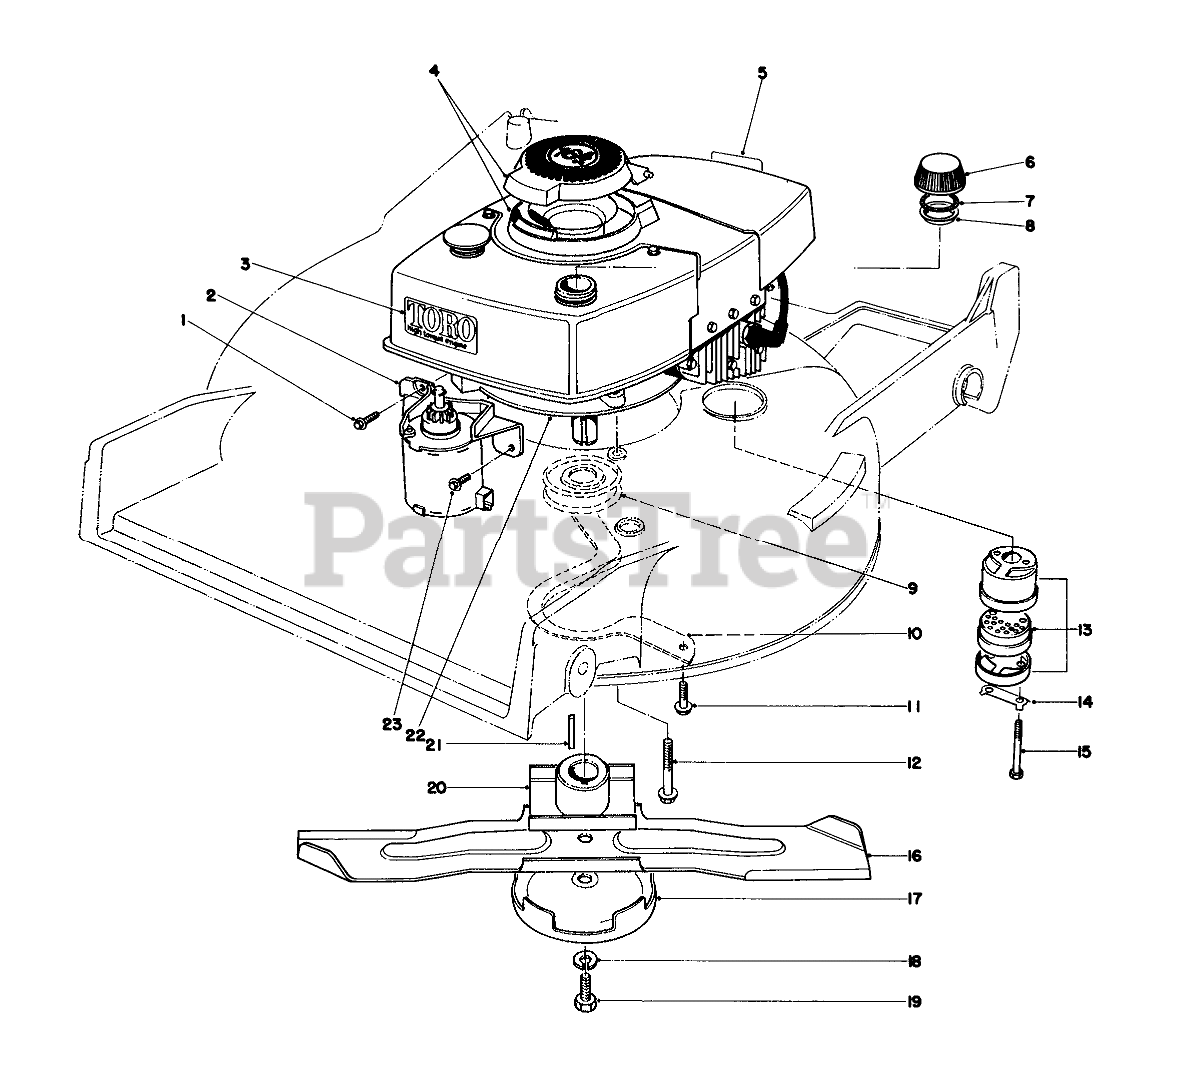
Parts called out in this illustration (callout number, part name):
1	Screw
2	Starter Motor
3	Decal-Toro High Torque
4	COVER ASM
5	Decal-Maintenance (French & Dutch)
6	Gas Cap (Incl. Ref. #7 & 8)
7	GASKET
8	GAS CAP BAFFLE
9	DRIVER PULLEY
10	BELT GUIDE
11	Screw
12	SCREW-HWHTF
13	Muffler Assy. (Incl.Ref. #14 & 15)
14	CLIP - LOCKING
15	SCREW-HH
16	Blade
17	AntiScalp Cup
18	WASHER-LOCK
19	BLADE SCREW
20	BLADE RETAINER WA(BLACK)
21	KEY-SQUARE
22	Engine
23	SCREW
